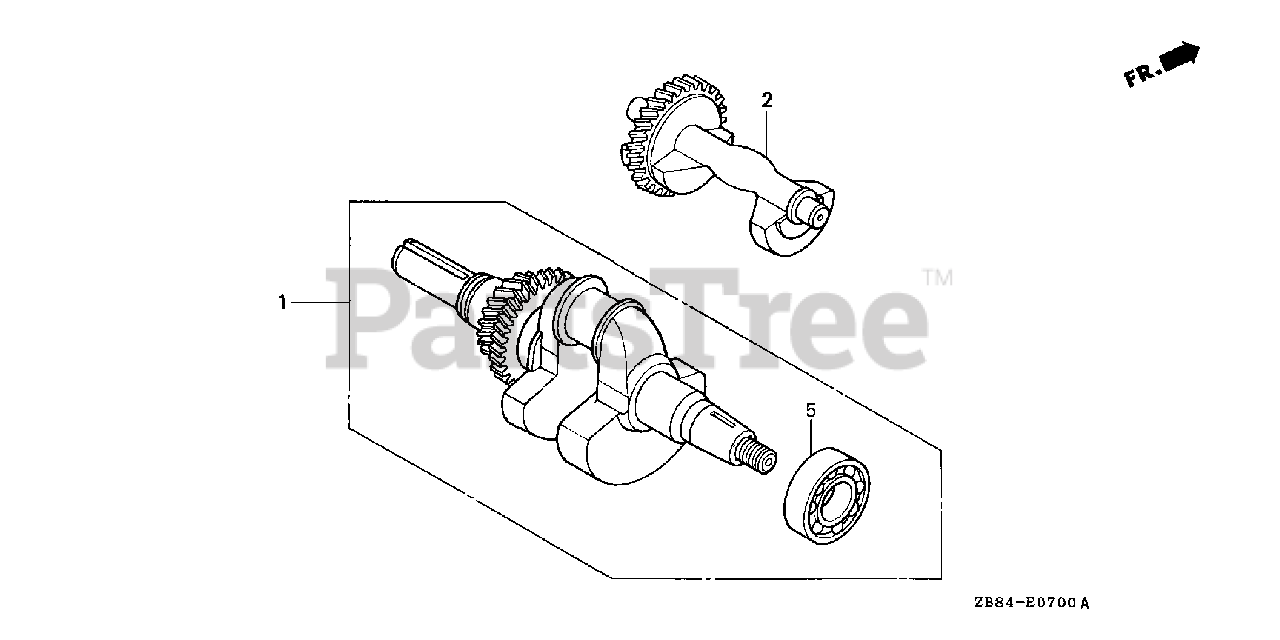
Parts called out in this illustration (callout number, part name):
1	CRANKSHAFT (E-TYPE)
1	CRANKSHAFT
2	WEIGHT, BALANCER
5	BEARING, RADIAL BALL (6207)
